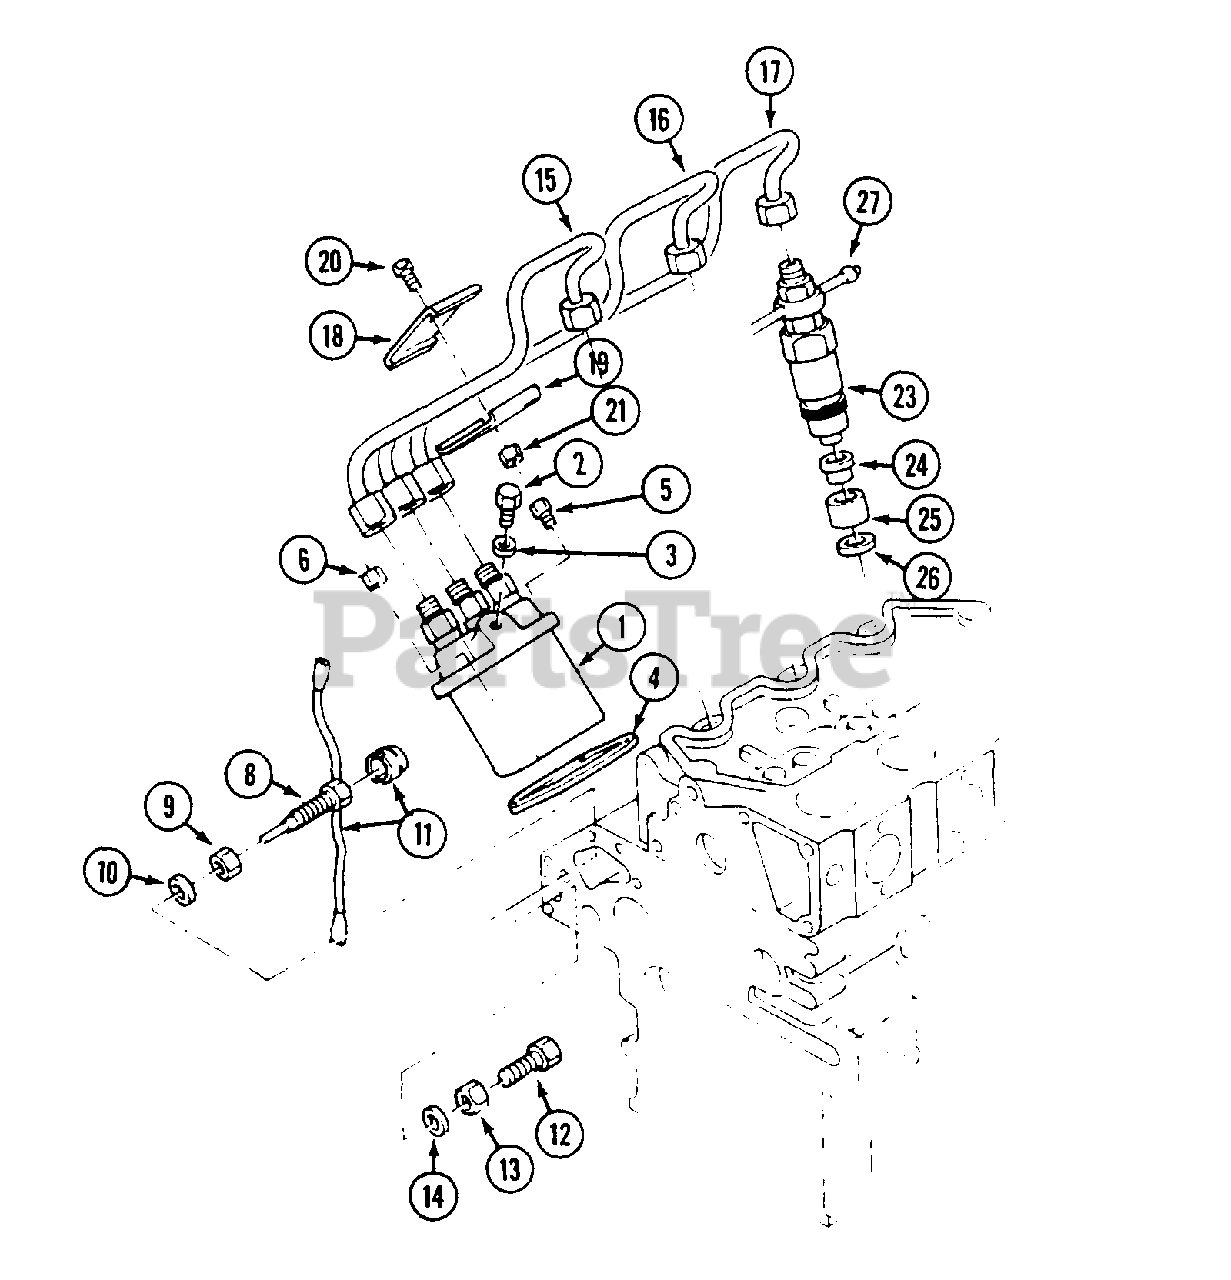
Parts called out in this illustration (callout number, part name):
1	PUMP - injection
2	SCREW
3	WASHER
4	SHIM - 0.2mm
5	SCREW
6	NUT
8	SCREW
9	NUT
10	WASHER
11	WIRE
12	SCREW
13	NUT
14	WASHER
15	PIPE - injection (No. 1 cylinder)
16	PIPE - injection (No. 2 cylinder)
17	PIPE - injection (No. 3 cylinder)
18	DAMPER
19	DAMPER
20	SCREW
21	NUT
23	ATOMIZER - fuel
24	GASKET
25	INSERT
26	SEAL
27	PIPE
